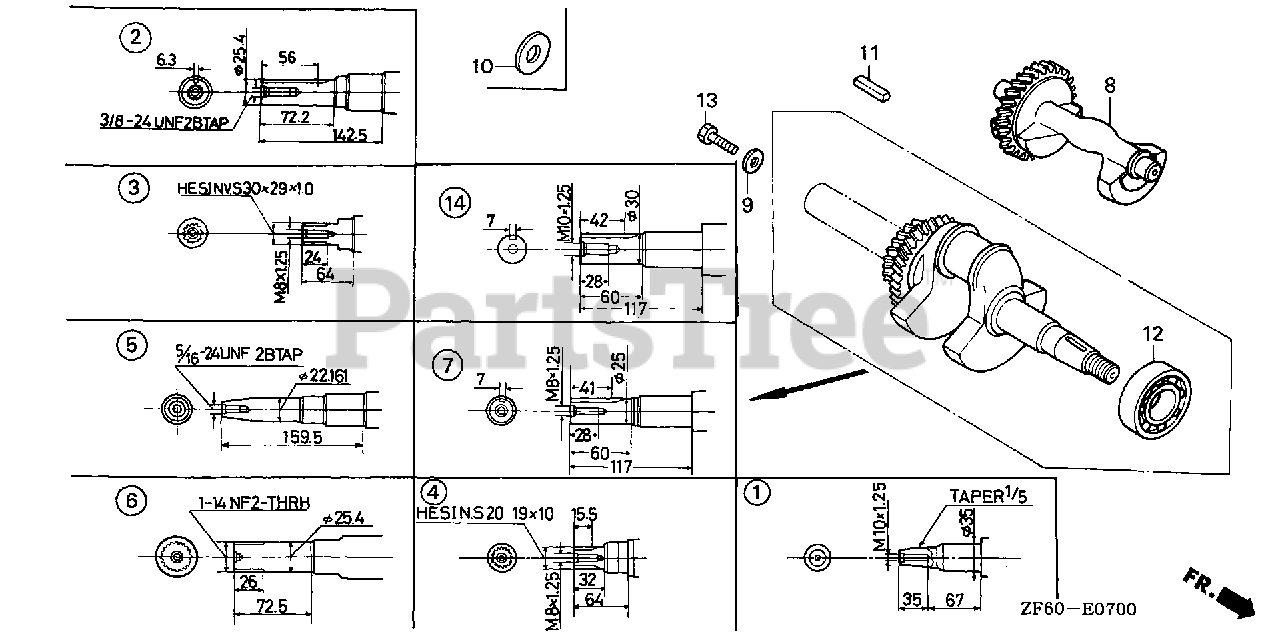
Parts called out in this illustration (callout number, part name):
5	CRANKSHAFT
8	WEIGHT, BALANCER
12	BEARING, RADIAL BALL (6207SH)
